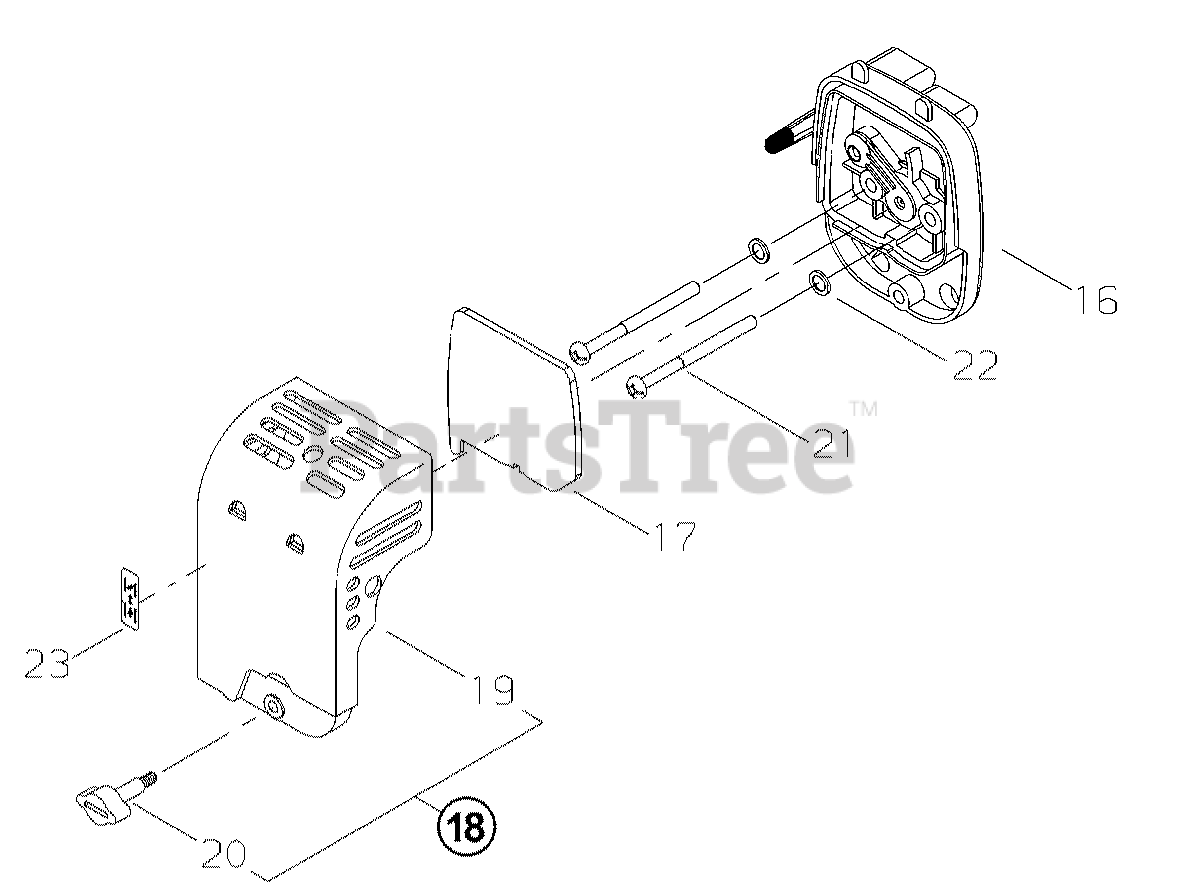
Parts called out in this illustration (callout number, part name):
16	CASE, AIR FILTER
17	FILTER, AIR
18	AIR FILTER COVER ASSY
19	COVER, AIR FILTER
20	THUMBSCREW
21	SCREW - 5X60
22	WASHER - 5
23	LABEL - CHOKE
